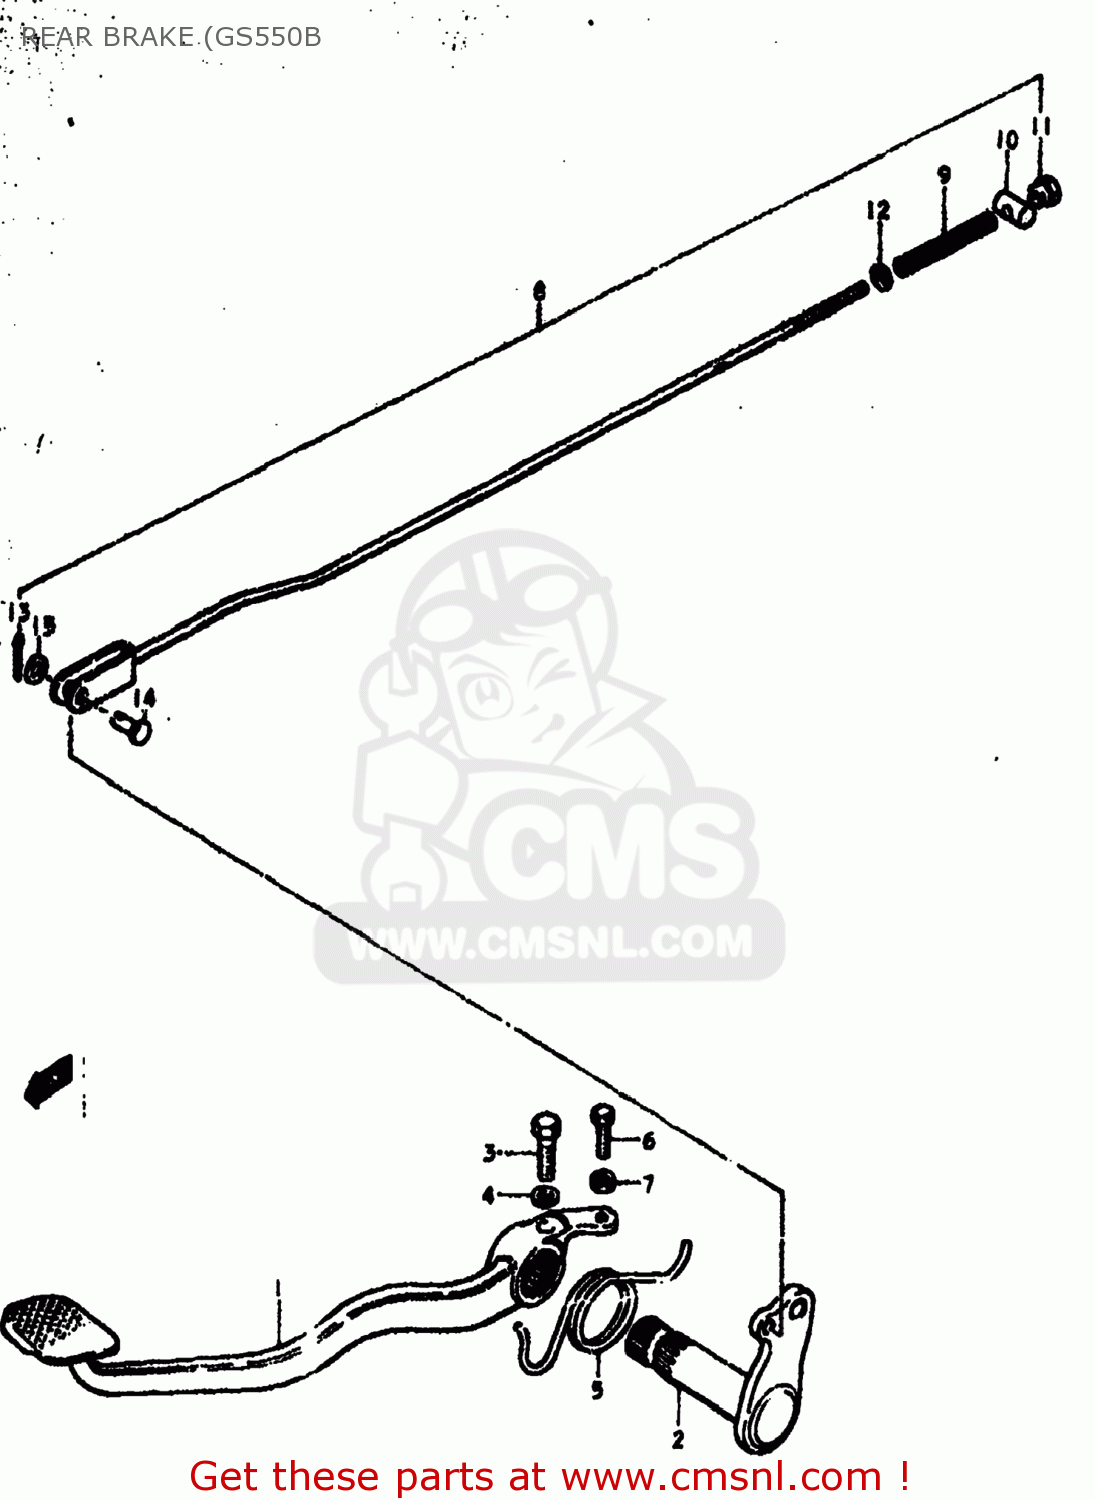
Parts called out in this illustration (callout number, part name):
1	PEDAL,BRAKE
2	ARM,BRAKE PEDAL
3	BOLT
4	LOCK WASHER
5	SPRING
6	BOLT
7	NUT
8	ROD ASSEMBLY,REAR BRAKE
9	SPRING
10	PIN
11	NUT
12	WASHER
13	PIN 20X20
14	PIN(L:13.5)
15	WASHER
